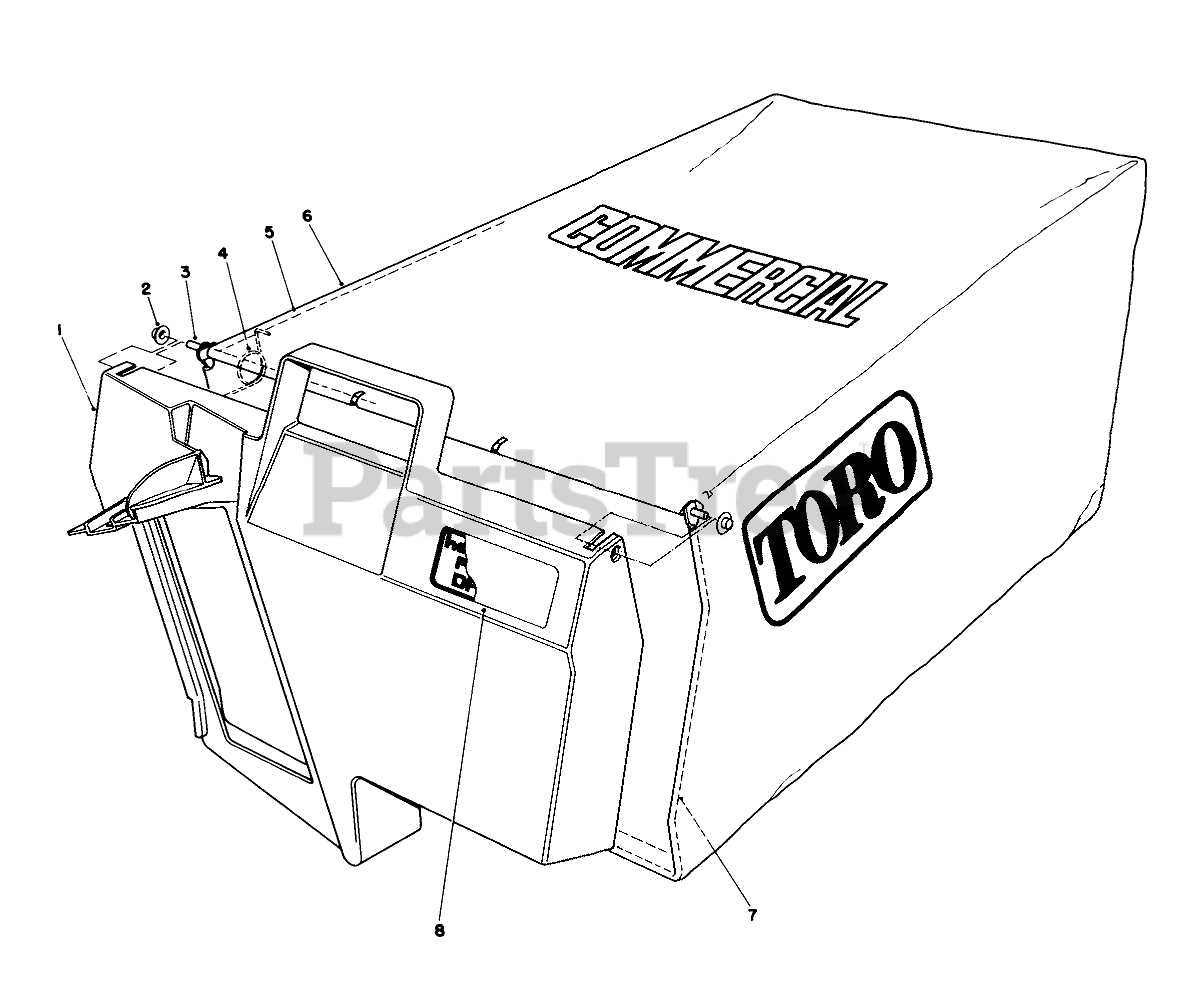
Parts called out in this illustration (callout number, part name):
1	DOOR-BAG, GRASS
2	NUT-PUSH
3	HINGE-DOOR, BAG
4	SPRING
5	FRAME-BAG, UPPER
6	Bag
7	FRAME-BAG
8	BAG DOOR DECAL
